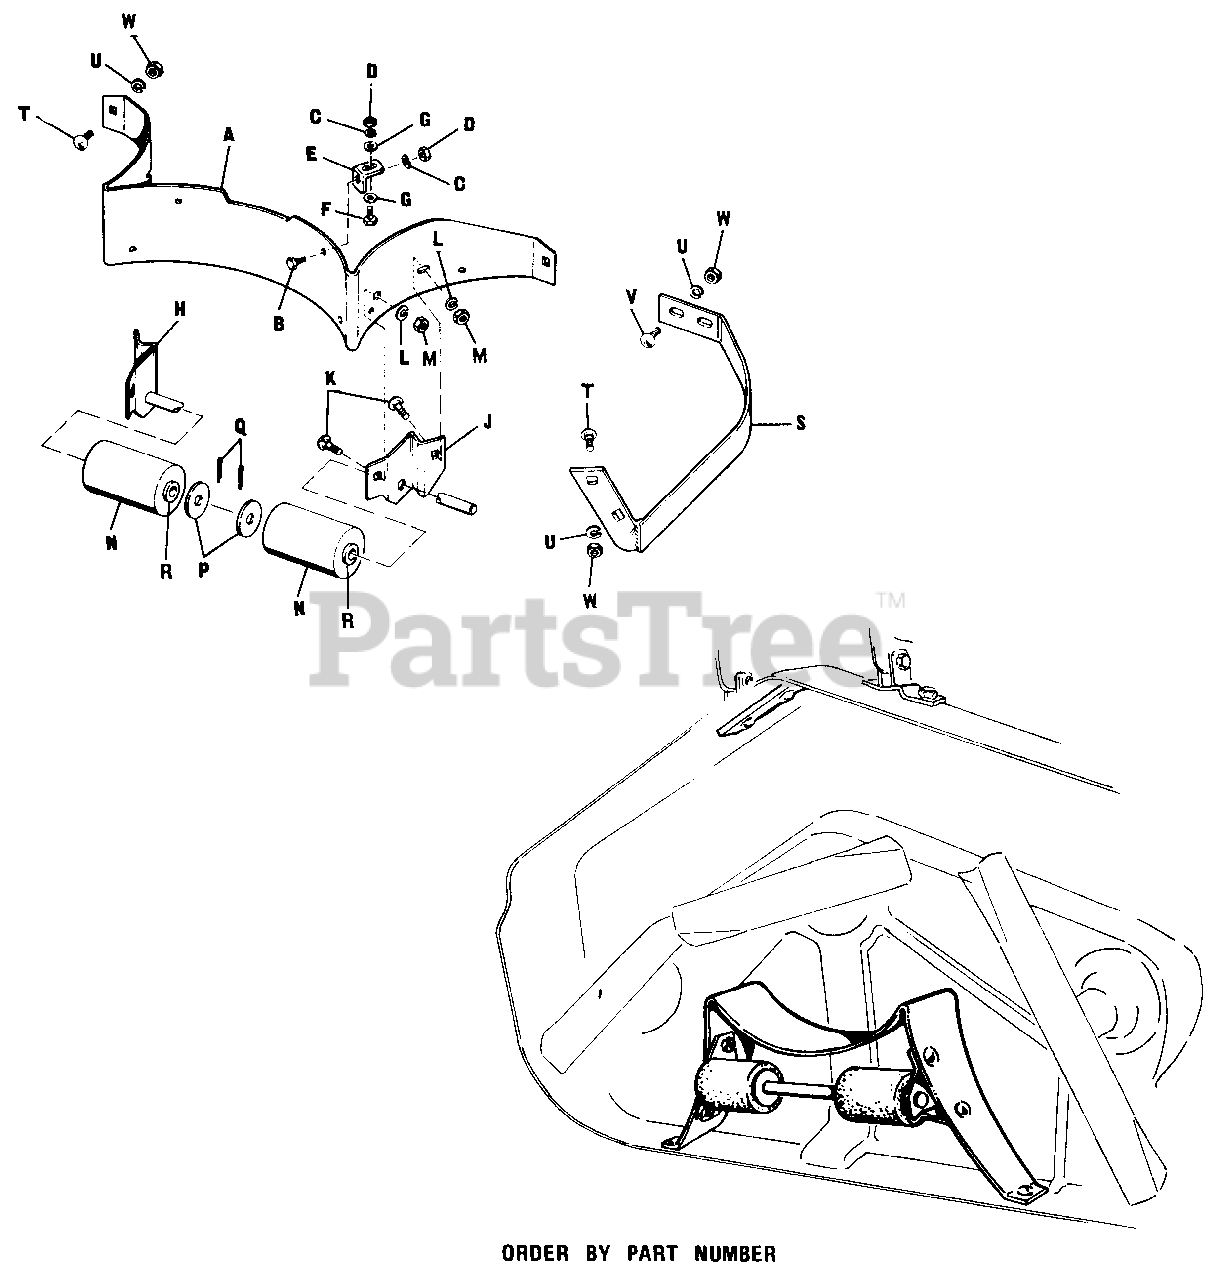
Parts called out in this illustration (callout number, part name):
B	Self Tap Hex. Screw, 1/4"-20 x 7/8"
C	Lock Washer, 1/4"
D	Full Hex. Nut, 1/4"-20
E	Baffle Clip
F	Hex. Cap Screw, 1/4"-20 x 5/8"
G	Plain Washer, 1/4"
H	Bracket & Shaft Assembly
J	L.H. Roller Bracket
K	Carriage Bolt, 5/16"-18 x 3/4"
L	Lock Washer, 5/16"
M	Full Hex. Nut, 5/16"-18
N	Roller Assembly W/Bushing
Q	Cotter Pin, 3/16" x 1"
S	Housing Assembly Guard
T	Carriage Bolt, 3/8"-16 x 3/4"
U	Lock Washer 3/8"
V	Carriage Bolt, 3/8"-16 x 1"
W	Full Hex. Nut, 3/8"-16
